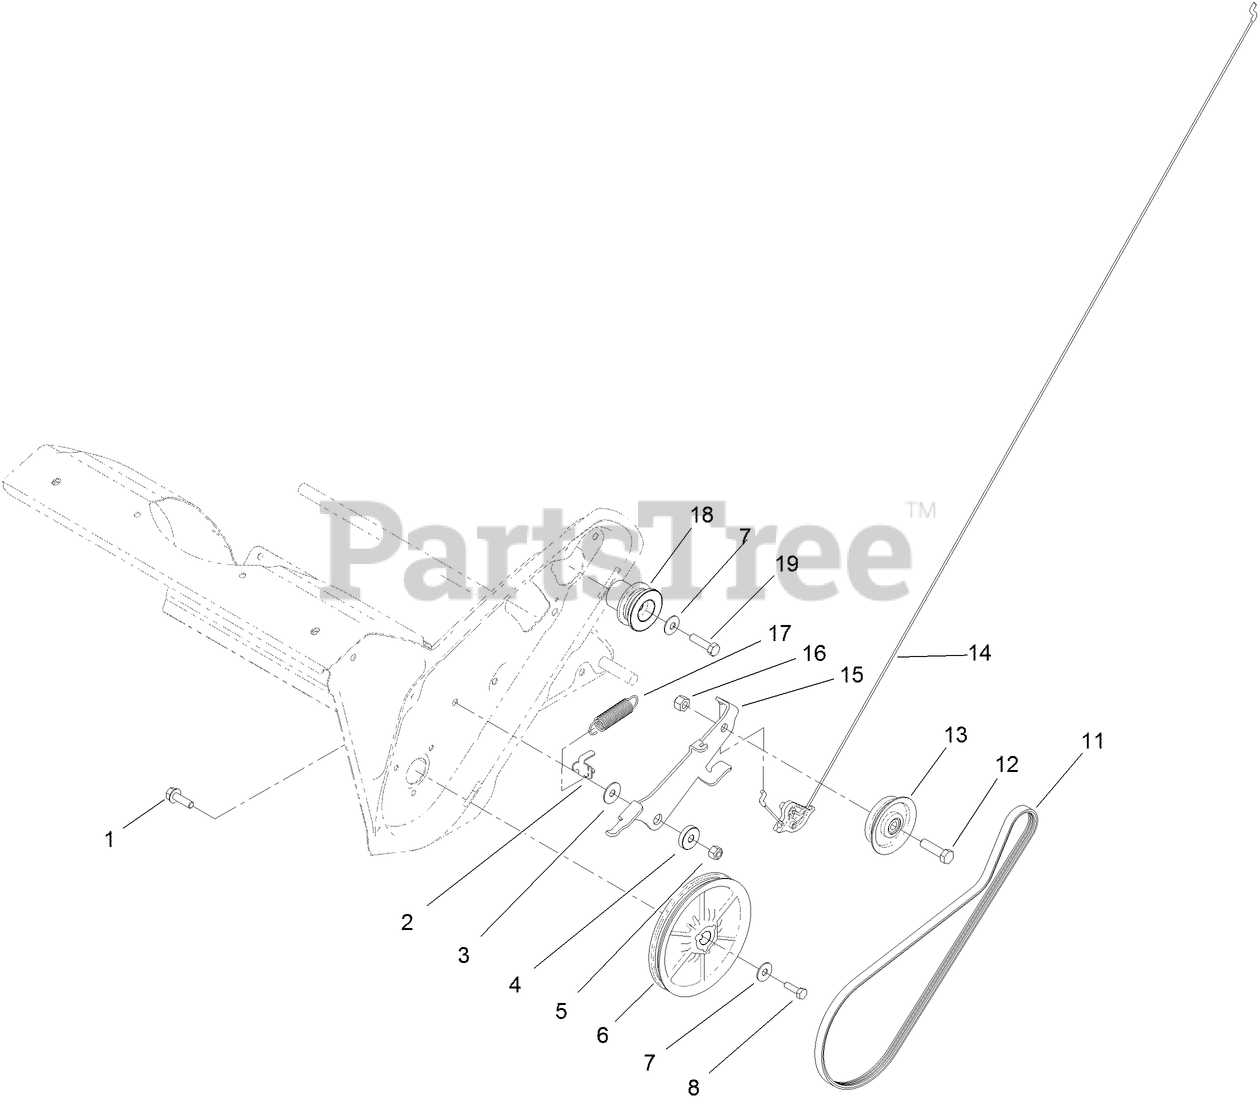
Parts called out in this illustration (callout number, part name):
1	SCREW-HHF
3	WASHER
4	BUSHING-PIVOT
5	NUT-LOCK, NI
6	PULLEY
7	WASHER-BELLEVILLE
8	SCREW-HH
11	BELT-DRIVE
12	SCREW-HH
13	PULLEY-IDLER
14	CABLE-CLUTCH
15	ARM-IDLER
16	NUT-LOCK, CONE
17	SPRING-EXTENSION
18	PULLEY-ENGINE
19	SCREW-HH
